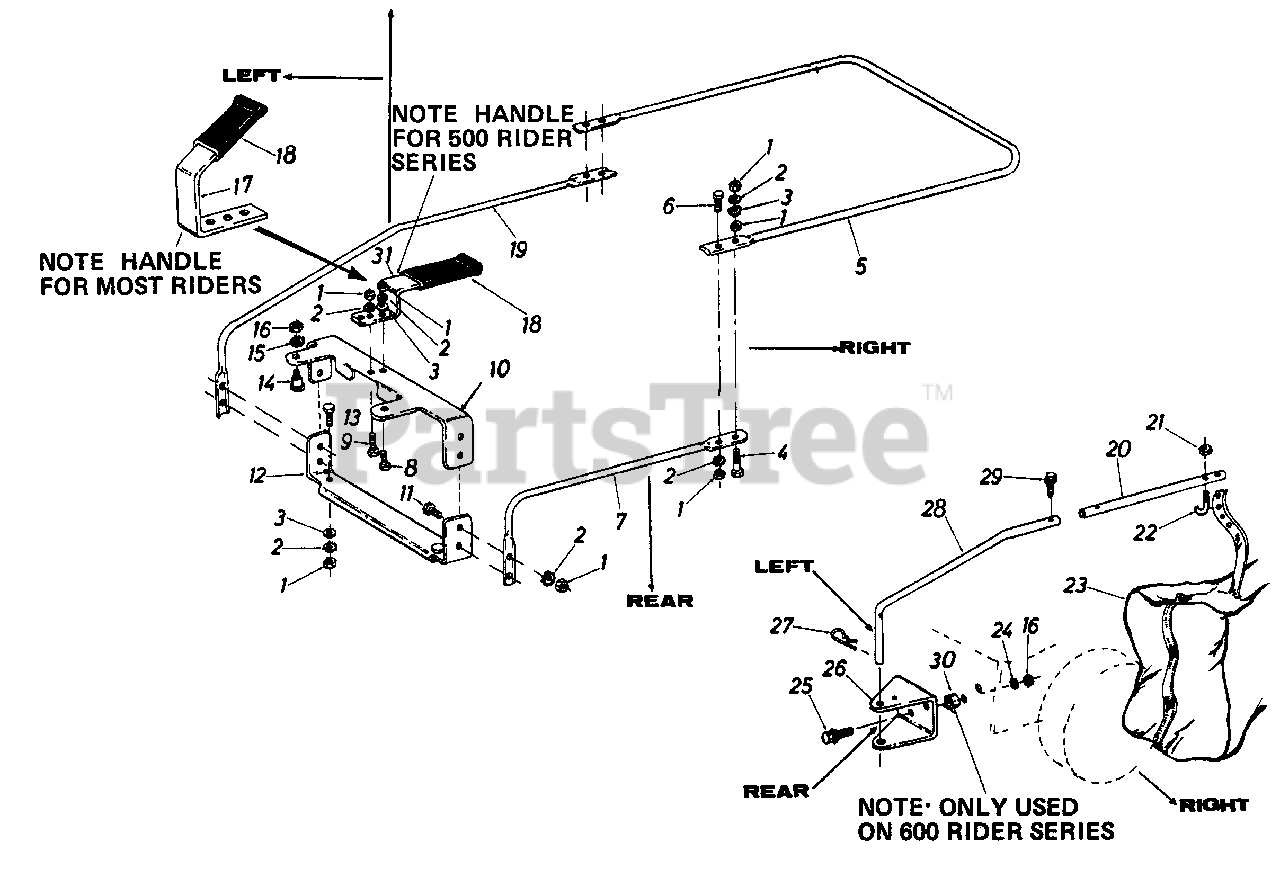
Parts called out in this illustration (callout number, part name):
1	Hex Nut 1/4-20 Thd.*
2	Ext. L-Wash. 1/4" Scr.*
3	Fl-Wash. .281 I.D. x .50 O.D.
4	Hex Scr. 1/4-20 x 1.50" Lg.*
5	Upper Frame Handle
6	Hex Scr. 1/4-20 1.00" Lg.*
7	Lower Frame Tubing
8	Hex Scr. 1/4-20 x .75" Lg.
9	Hex Scr. 1/4-20 x .75" Lg.*
10	Upper Opening Support
11	Hex Scr. 1/4-20 x 1.0" Lg.*
12	Lower Opening Support
13	Hex Scr. 1/4-20 x .50" Lg.*
14	Shld. Scr. .437 Dia. x .350
15	Ext. L-Wash. 5/16" Scr.*
16	Hex Nut 5/16-18 Thd.*
19	Lower Frame Arm
23	Grass Catcher Bag
24	L-Wash. 5/16" I.D.*
25	Hex Sems Scr. 5/16-18 x .75" Lg.*
26	Hitch Bracket
27	Internal CotterPin 5/8" Dia.
28	Lower Holding Arm
29	Hex Wash. Hd. Self-Tap .50" Lg.
